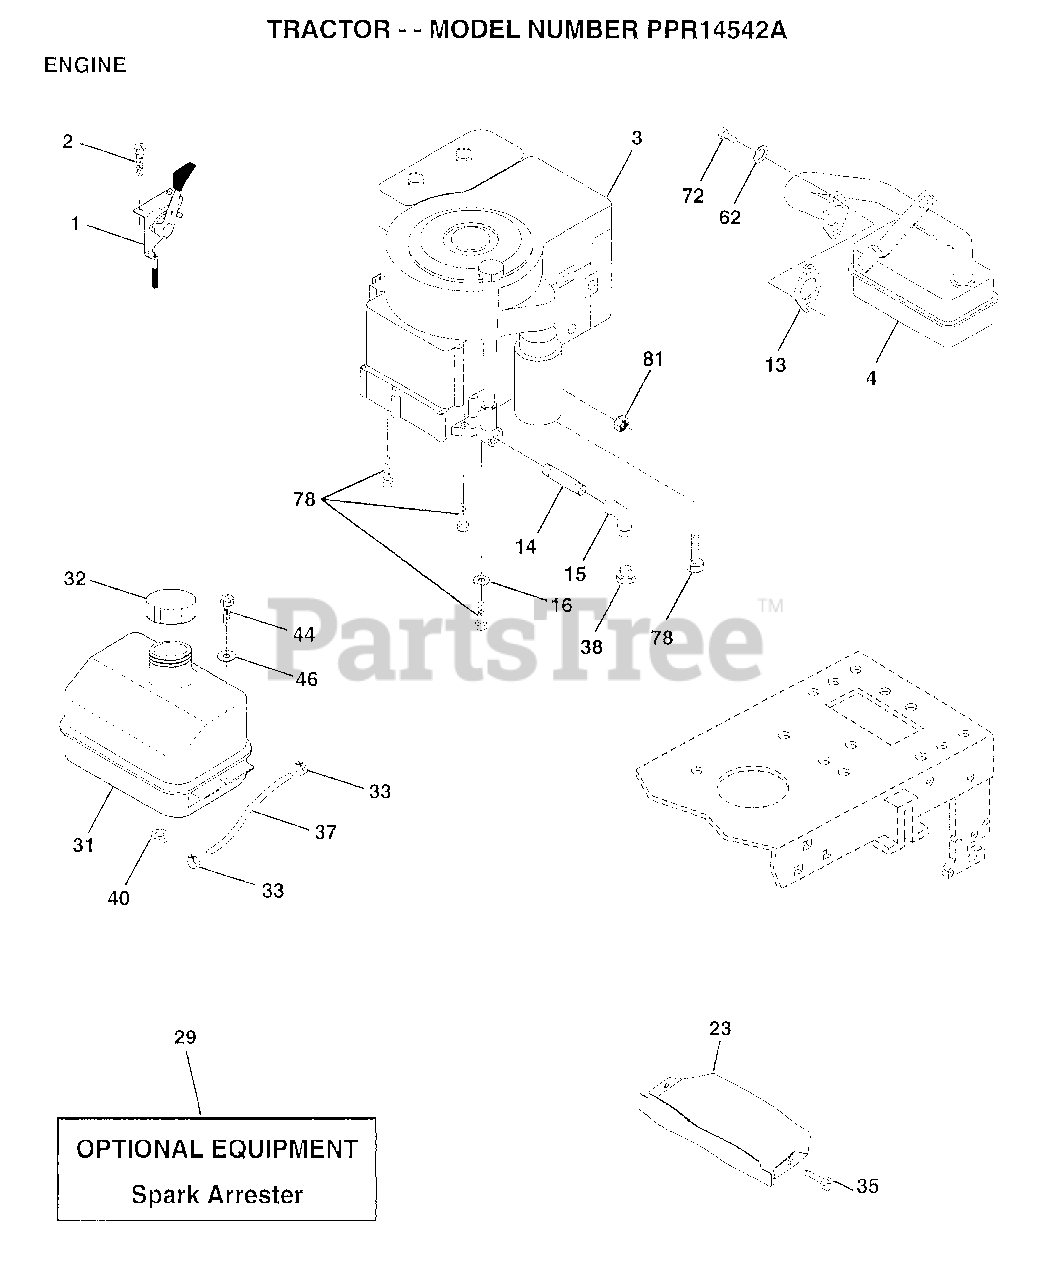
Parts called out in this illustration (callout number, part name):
1	CONTROL THROTTLE
2	SCREW LT
4	MUFFLER
14	PIPE NIPPLE
15	ELBOW
16	LOCKWASHER
23	SHIELD.BRN/DBR.GD
31	TANK.FUEL.LT.
32	CAP ASM FUEL
33	HOSE CLAMP
35	SCREW
37	LINE FUEL
44	SCREW HEX CRT
46	WASHER
62	LOCKWASHER
72	SCREW
78	SCREW
81	NUT
